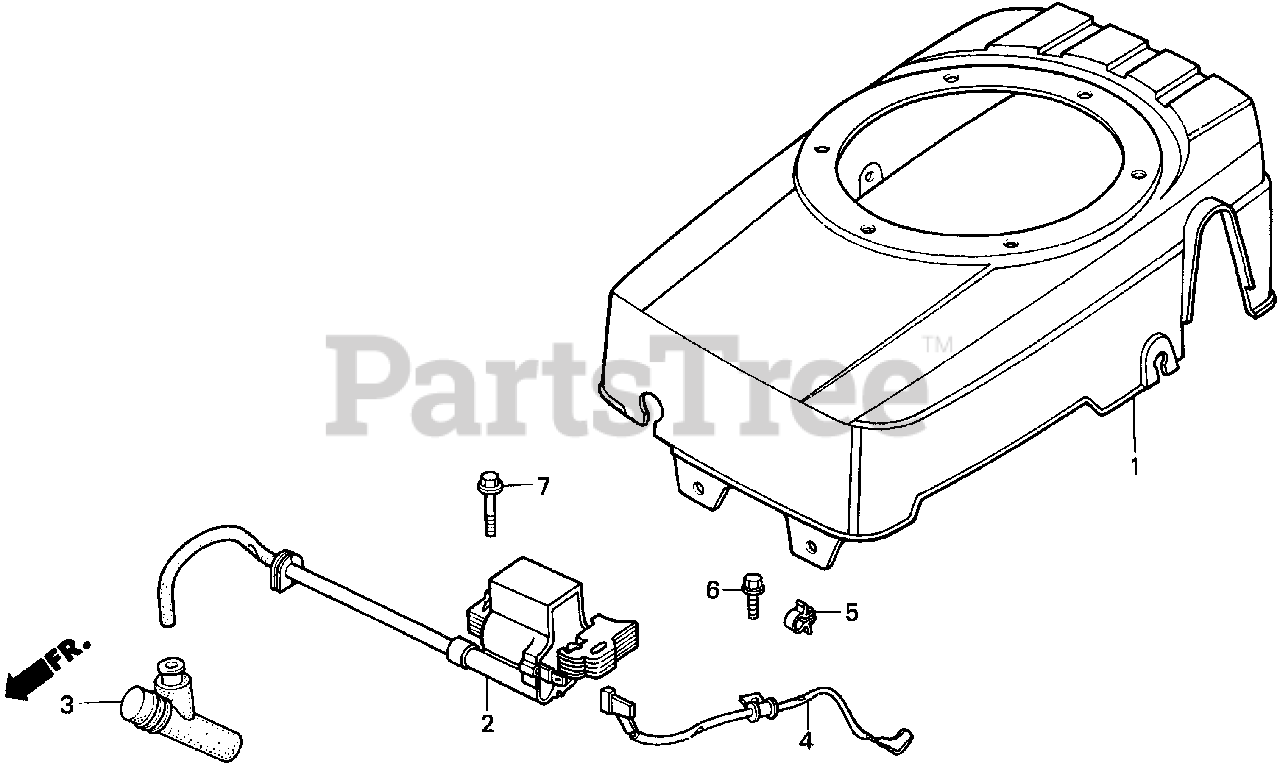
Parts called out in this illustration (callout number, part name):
1	COVER, FAN
2	COIL ASSY., IGNITION (NOT AVAILABLE)
2	COIL ASSY., IGNITION
3	TERMINAL ASSY., IGNITION
3	CAP ASSY., NOISE SUPPRESSOR
4	WIRE, STOP SWITCH
5	HOLDER, STOP SWITCH WIRE
6	BOLT, FLANGE (5X10)
7	BOLT, FLANGE (6X25) (CT200)
